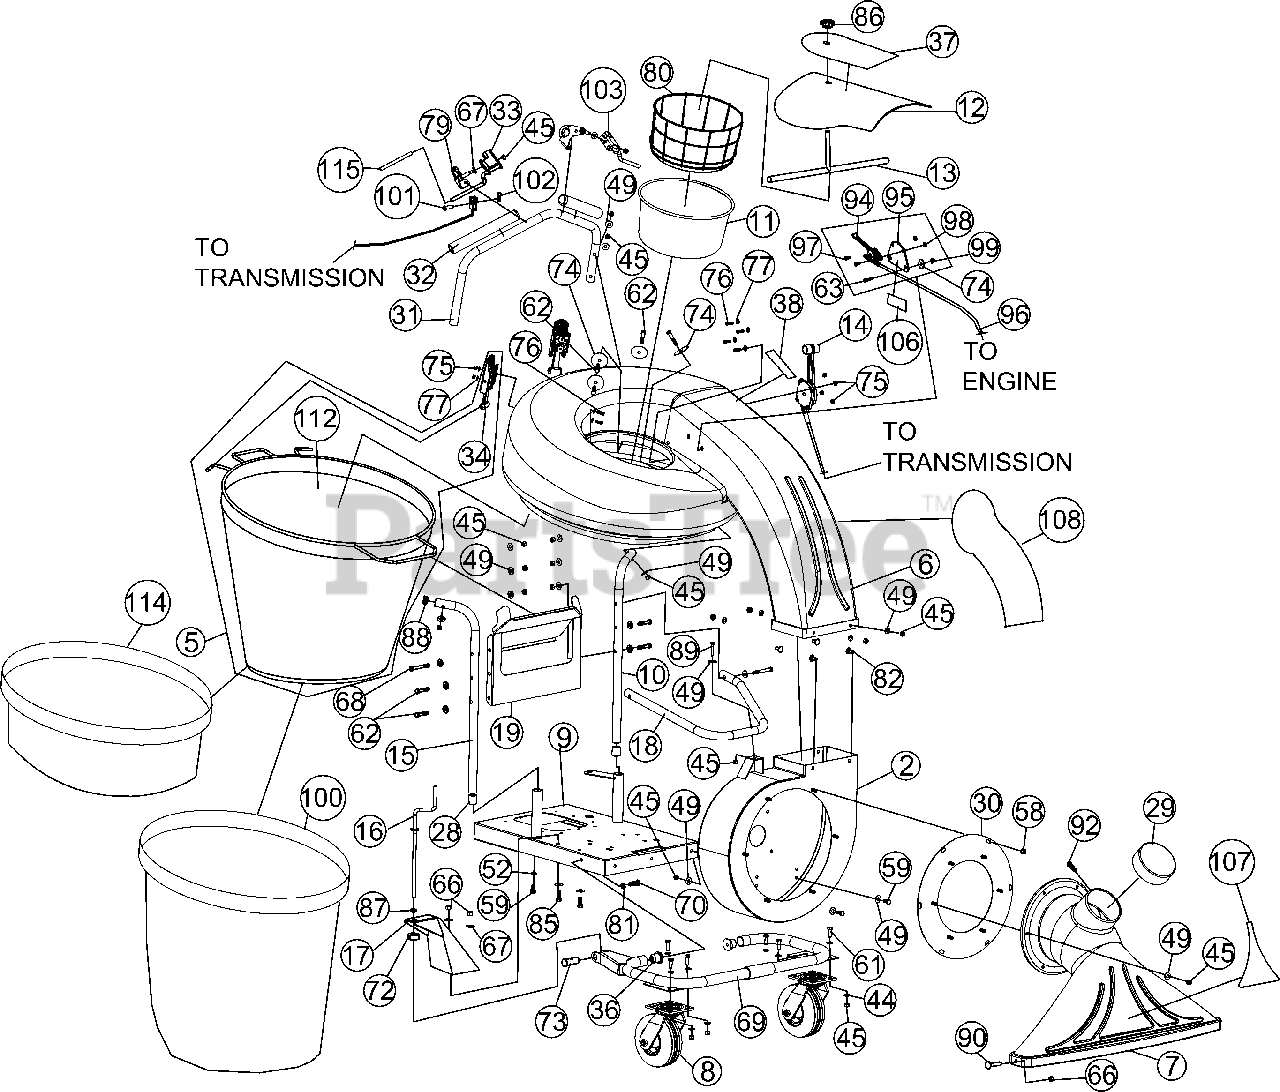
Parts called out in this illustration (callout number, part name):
2	HOUSING QV WA W/LABELS
6	HOOD QVSP W/LABELS
7	NOZZLE 32"
8	CASTER SWIVEL QV
9	ENGINE BASE 5 HP WA SP
10	HANDLE LOWER LFT
11	HOOD FILTER
12	HOOD SCOOP QVSP W/LABEL
13	ROD FILTER HOLDER QV
14	SHIFTER CONTROL
15	HANDLE LOWER RT
16	HEIGHT ADJ ROD
17	HEIGHT ADJ BRACKET WA
18	HANDLE WISHBONE
19	BRACKET HANDLE SUPPORT
29	CAP 5" VINYL BLACK
30	PLATE NOZZLE WA QV
31	HANDLE UPPER QV
32	GRIP 1" OD X 9.5"
33	ARM CLUTCH CONTROL QV WA
34	BAG LATCH
36	BUSHING FRAME PIVOT
37	LABEL INSTRUCTION QV
38	LABEL DRIVE DIRECTION
44	WASHER 5/16" SAE
45	NUT LOCK 5/16"-18 HEX ZP
49	WASHER 5/16" FLAT
52	WASHER LOCK 5/16" SPLIT
58	NUT 5/16-18 SER HEX WSHR FLNG ZP
59	SCREWCAP 5/16"-18 X 3/4" HCS ZP
61	SCREWCAP 5/16"-18 X 1" HCS ZP
62	SCREWCAP 5/16"-18 X 1 3/4" HCS ZP
63	SCREWCAP 1/4"-20 X 3/4"
66	NUT LOCK 3/8" -16 HEX
67	WASHER 3/8" FLAT
68	SCREWCAP 5/16"-18 2 3/4" HCS ZP
69	FRAME CASTER QV WA
70	SCREWCAP 3/8"-16 X 1 1/4" HCS ZP
72	STOP COLLAR
73	PIVOT HEIGHT ADJ WA
74	WASHER 2" OD X 0.344 ID X 16 GA
75	NUT LOCK #10-24 HEX
76	SCREW MACH #10-24 X 3/4"
77	WASHER #10 SAE
79	CONTROL MOUNT HANDLE WA
80	FILTER FRAME
81	WASHER LOCK 3/8" ST MED
82	BOLT CARRIAGE 5/16"-18 X 3/4" ZP
85	SCREWCAP 3/4"-16 X 1" HCS ZP
86	KNOB 3/8"-18 SOLID HUB
87	BUSING HEIGHT ADJ BRKT QV
88	PLUG TUBE INSERT 1" OD
89	SCREWCAP 5/16"-20 X 1 1/2"
90	BOLT CARRIAGE 3/8" -16 X 1"
92	SCREW PLASTITE 1/4"-20 X 3/4" HWH ZP
94	CONTROL THROTTLE
95	PLATE THROTTLE
96	CABLE THROTTLE
97	SCREW MACH HD PHIL #10-24
98	NUT LOCK LT #10-24
99	NUT FLANGE 1/4"-20
100	DUST SOCK DOUBLE LAYER QV
101	PIN CLEVIS 0.25 X 0.50
102	PIN CLIP HITCH .051 X 3/4"
103	ARM CONTROL WA
106	LABEL THROTTLE
107	LABEL NOZZLE QV
108	LABEL BADGING QV
112	BAG QV NO CLASPS SERVICE
114	DUST SKIRT
115	GRIP CLUTCH CONTROL
